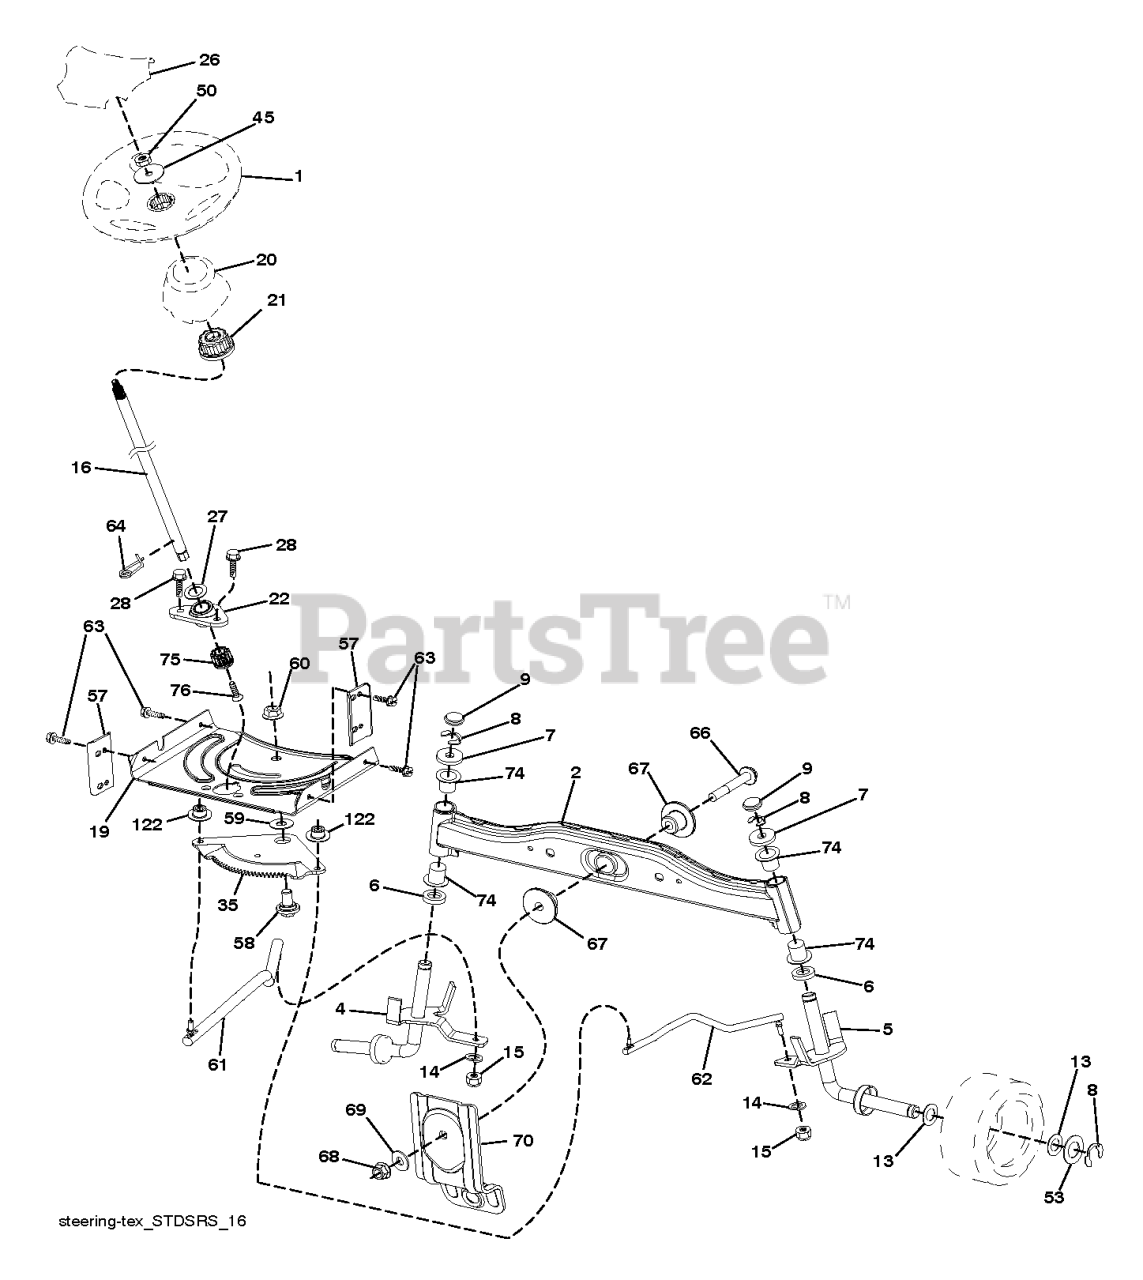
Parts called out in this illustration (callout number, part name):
1	WHEEL.STEERING.HARD.RIM.BLAC
2	AXLE HALF ASM-WELDED
4	SPINDLE.WELDED.LH.15"TEX
5	SPINDLE.WELDED.RH.15"T
6	Bearing Race Thrust Harden (AYP part number)
7	Washer 25/32 x 1-5/8 x 16 Gauge (AYP part number)
8	Ring, Klip #T5304-75 (AYP part number)
9	Cap Spindle Fr Top Blk (AYP part number)
13	Washer 25/32 x 1-1/4 x 16 Gauge (AYP part number)
14	SLW 3/8 STD
15	Nut, Crownlock 3/8-24 (AYP part number)
16	SHAFT.STEER.2HIGH.SPLND.PLATED
19	PLATE.STEER.DDL.NLT/NG
20	BOOT.STRNG.PREDATOR.YT/GT.428
21	ADAPTER.WHEEL.STEER.SPLND.ALUM
22	BEARING.SHAFT.STEER.LOWER.625
26	INSERT, WHEEL STEERING
27	Washer 21/32 x 1 x 16 Gauge (AYP part number)
28	SCREW, 3/8-16X3/4
35	GEAR.SECTOR.PLATE.DDL.
45	WASHER.3/8ID.2-3/8OD.12GA.PLTD
50	NUT LOCK FLG 3/8-16 UNC
53	WASHER.HARDENED
57	BRACKET.UPSTOP.TEX
58	BOLT.SHOULDER.SECTOR.P
59	WASHER.THURST.SECTOR.S
60	NUT FLANGE LOCK 5/8-11
61	DRAGLINK.LH.BALLSTUD.D
62	DRAGLINK.RH.BALLSTUD.D
63	SCREW
64	RETAINER.CLIP.SPRING.S
66	BOLT HEX FGHD 7/16-14 X 3 SERR
67	BUSHING.PM.FRONT AXLE
68	NUT.LOCK.FLANGE.7/16
69	WASHER.1.5X.505X.118
70	BRACKET.FRT.DECK.SUSP.RR.MT431
74	Bearing Col Strg Blk (AYP part number)
75	PINION.ZINC PLATED
76	SCREW HEAD SOCKET LRVB
122	CAP.GEAR.SECTOR.TEX
